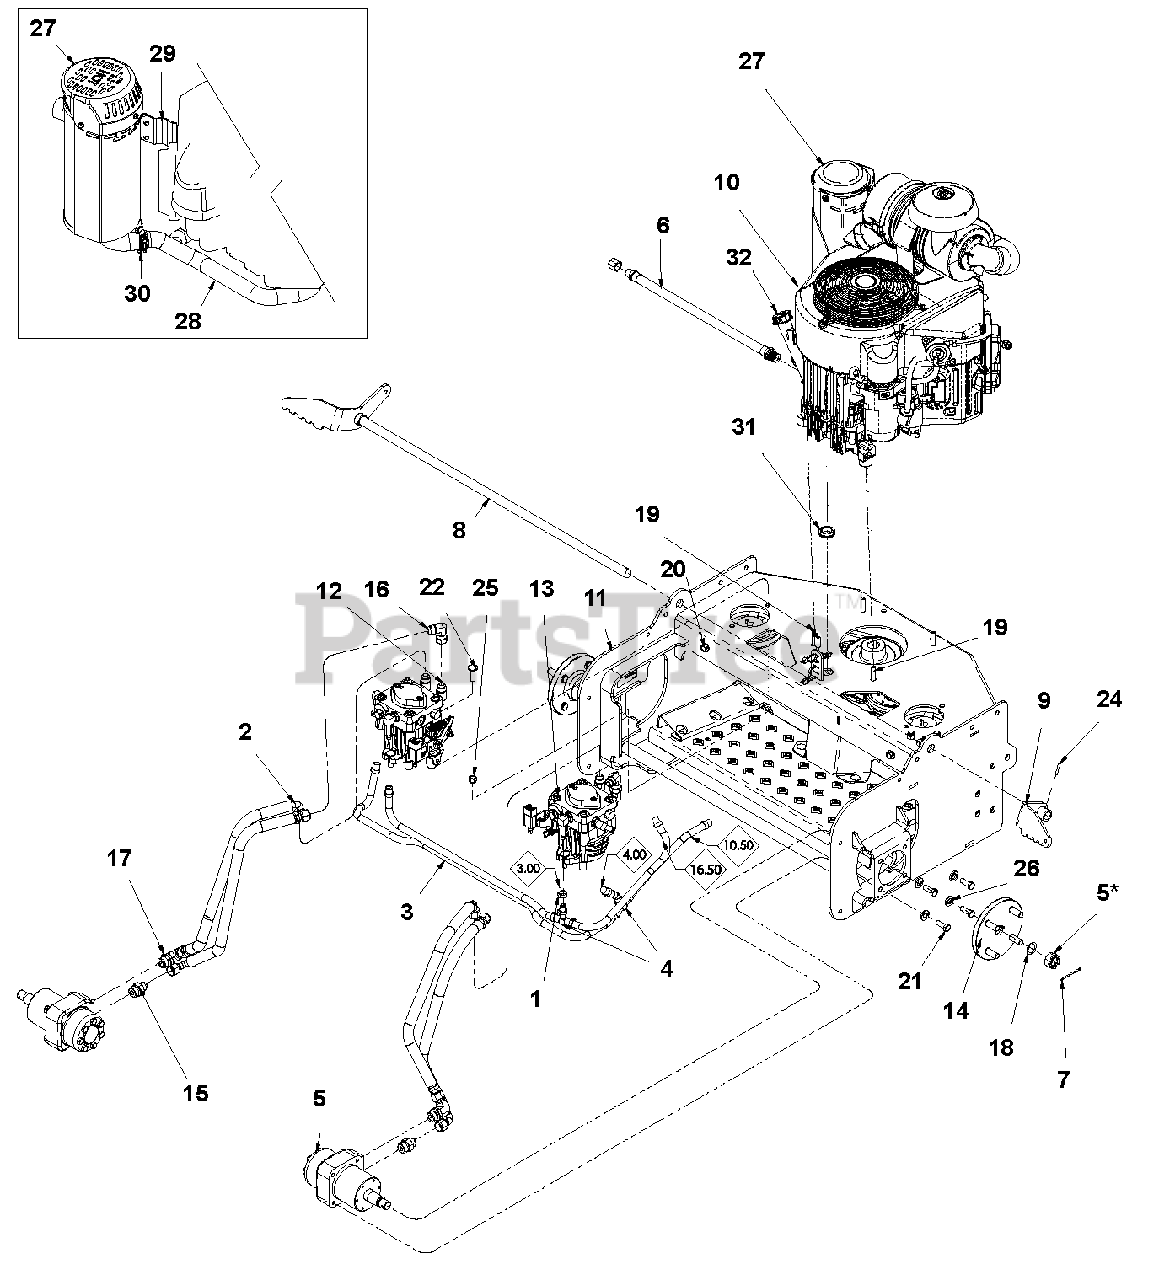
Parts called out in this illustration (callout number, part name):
1	Clamp, Hose - 1/2" Pinch
2	Hose Assembly
3	Hose, 3/8 SAE 30R7 Fuel & Oil
4	Fitting, TUN 3/8 Hose
5	Motor, Wheel HGM-12P-7172 (*Includes Castle Nut, tighten to 163 N•m (120 lbf-ft))
6	Drain, M20 Oil
7	Pin, Cot .125 x 2.00 Extp Y
8	Weldment, Brake Shaft
9	Weldment, RH Brake Arm
10	Engine, Kawasaki FX 600
11	Weldment, Deck Frame w/Decals Gravely
12	Assembly, HYD Pump (See Pump Components on page 16.)
13	Assembly, HYD Pump (See Pump Components on page 16.)
14	Assembly, Rear Wheel Hub
15	Fitting, ADP 3/4-16FJIC x 7/8-14MOR
16	Fitting, ADP MJIC-FSWJIC 6500-08-08
17	Fitting, ADP JIC-ORB 2062-10-8S
18	Bushing, Mach., .75 x 1.25 x .048
19	Bolt, Hex .38 -16 x 1.25 FTHG5
20	Bolt, .375-16 x 1.00 FGH 8 Y
21	Bolt, .375-16 x 1.00 Hex 5 Y
22	Bolt, .375-16 x 1.25 CRG 5 Y
23	Locknut, .3125-18 Nyloc Y
24	Pin, Roll .156 x 1.00
25	Locknut, .375-16 Nyloc Y
26	Washers, .375 Medium Spring Lock
27	Muffler, Kawasaki FX OFS STD
28	Manifold, EXH Kawasaki FX STD
29	Bracket, Muffler Kawi FX STD
30	Clamp, Muffler Kawi FX STD
31	Grommet, Rub:88ID x 1.38OD x .14 GR
32	Cap, Oil Filler
